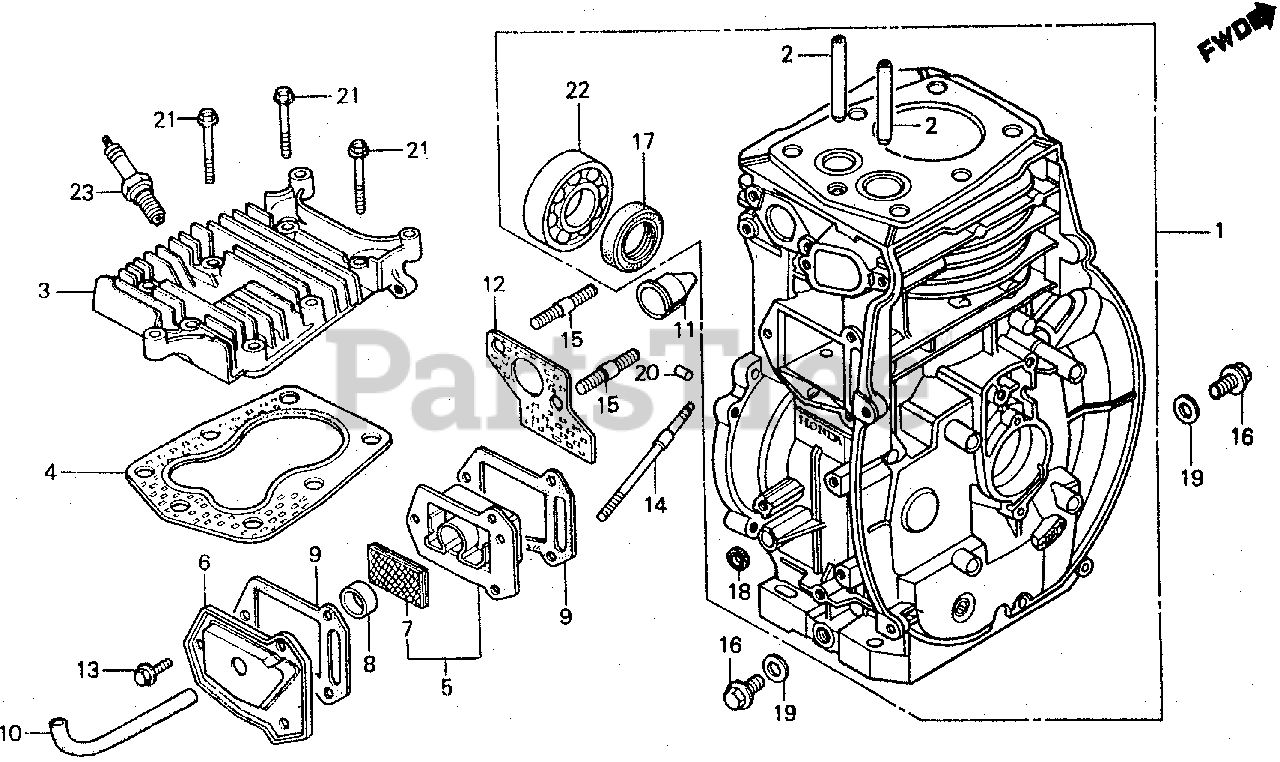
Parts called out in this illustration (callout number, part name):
1	CYLINDER ASSY.
2	GUIDE, VALVE (OS)
3	CYLINDER HEAD
4	GASKET, CYLINDER HEAD
5	CASE, BREATHER
6	COVER, TAPPET ROOM
7	FILTER, BREATHER
8	SEAL, BREATHER
9	GASKET, TAPPET COVER
10	TUBE, BREATHER
11	LINER, EX. PORT
12	GASKET, MUFFLER
13	BOLT, FLANGE (6X12) (CT200)
14	BOLT, STUD (6X89)
15	BOLT, STUD (8X35)
16	BOLT, DRAIN PLUG
17	OIL SEAL (25X41X6)
18	OIL SEAL (6X11X4)
19	WASHER, DRAIN PLUG (12MM)
20	PIN A, DOWEL (8X14)
21	BOLT, FLANGE (8X45)
22	BEARING, RADIAL BALL (6205)
23	SPARK PLUG (BR-4HS) (NGK)
23	SPARK PLUG (W14FR-U) (DENSO)
